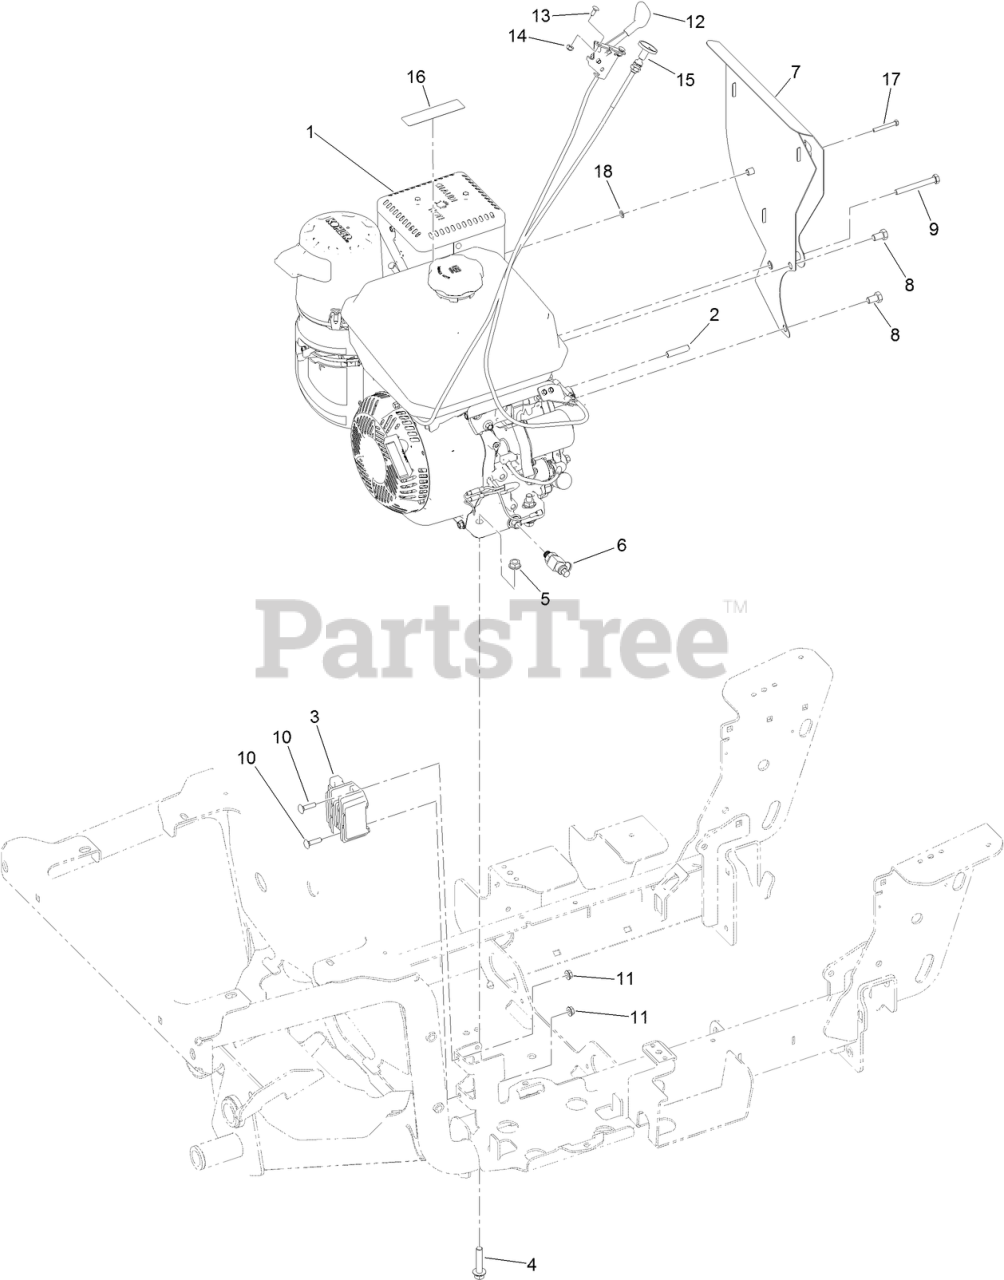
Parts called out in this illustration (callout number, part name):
1	ENGINE-KOHLER, CH395
2	KEY-SQUARE, 7MM
3	REGULATOR-TROMBETTA, 18A
4	SCREW-HHF
5	NUT-HF
6	VALVE-DRAIN, OIL
7	HEAT SHIELD ASM
8	SCREW-HH
9	SCREW-HH
10	SCREW-CARR
11	NUT-HF
12	CONTROL-THROTTLE
13	BOLT-CARR
14	NUT-LOCK, NI
15	CABLE-CHOKE, PUSH/PULL
16	DECAL-ARRESTOR, SPARK
17	BOLT-M5X0.8MM X 40 MM LONG
18	WASHER-FLAT
